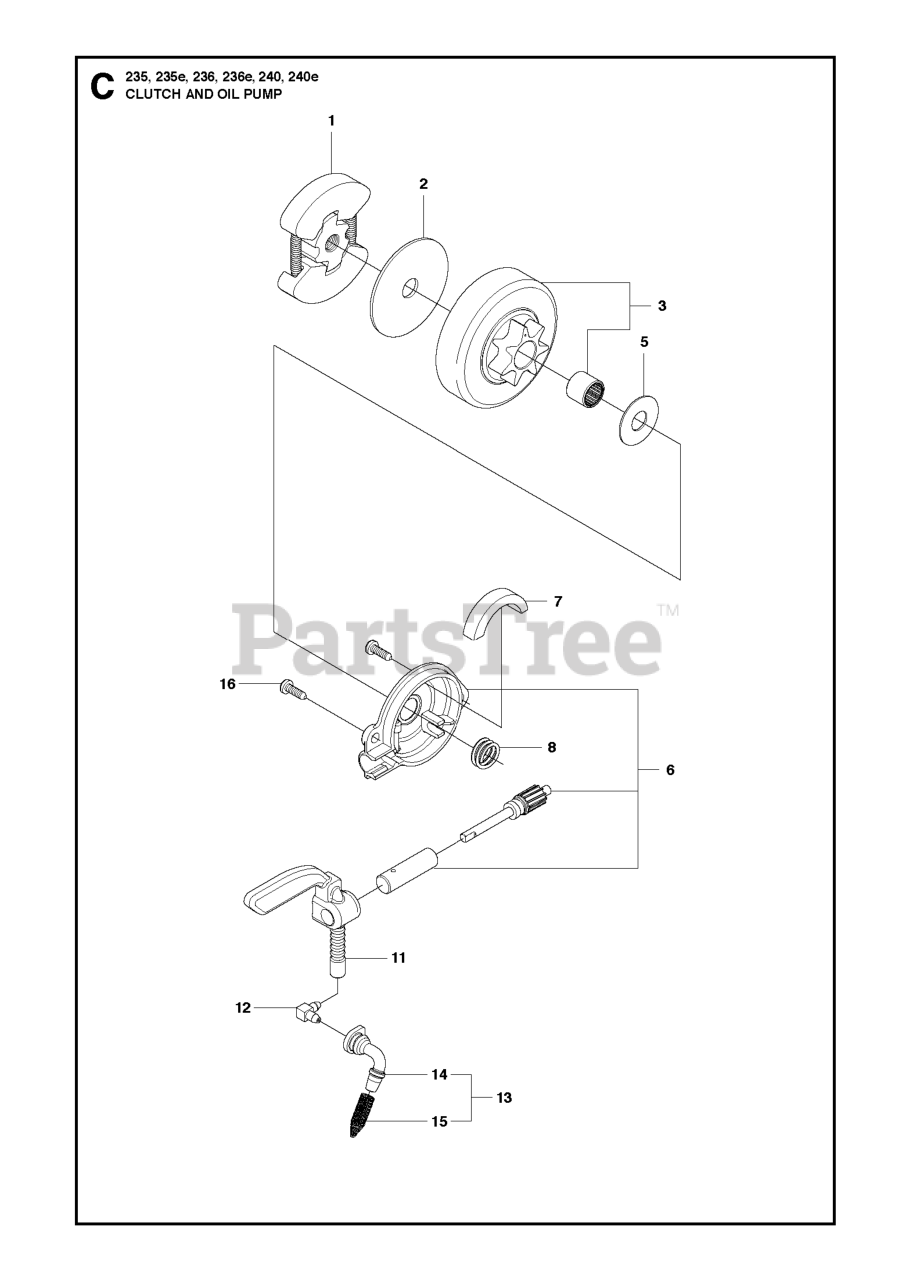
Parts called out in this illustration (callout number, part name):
1	CLUTCH ASSEMBLY
2	FRICTION DISC,CLUTCH 36/41
3	ASSY CLUTCH DRUM .325"
3	CLUTCH DRUM ASSY
5	THRUST WASHER
6	OIL PUMP COMPLETE
13	PICK UPS ASSY OIL TANK
14	SEAL PICKUP
15	SCREEN/FILTER
16	SCREW 6-19X.437
